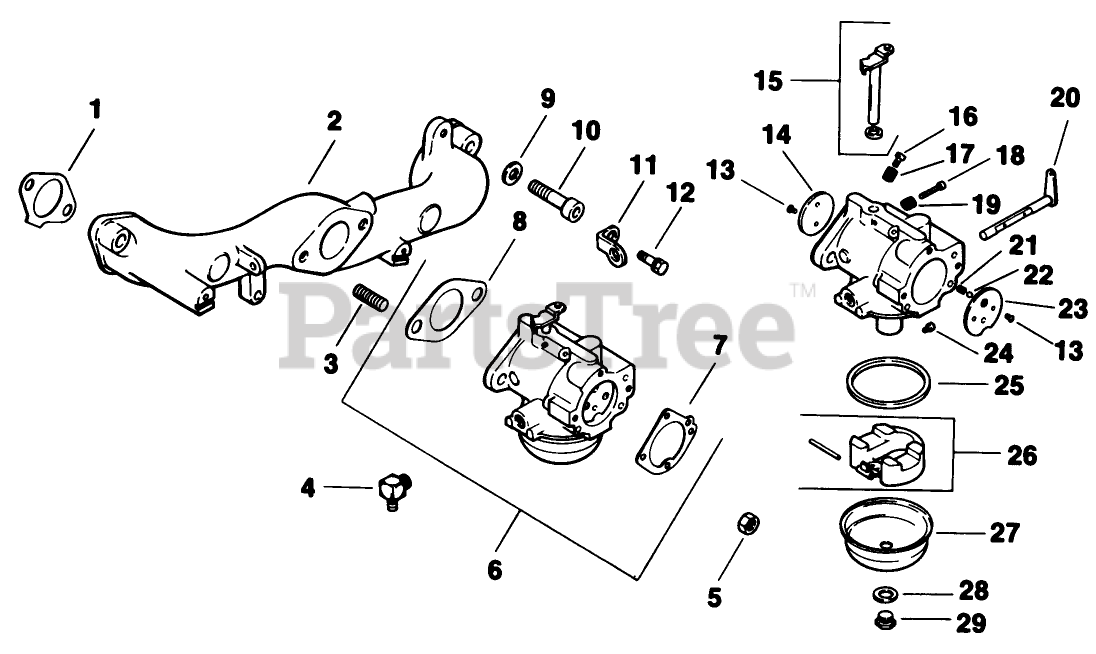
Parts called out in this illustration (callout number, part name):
1	Gasket-Intake
2	Manifold-Intake
4	Connector
6	Carburetor Kit w/Linkage (Incl. Ref. #7-9,14-30)
7	Gasket
8	Carburetor Assembly Ref.
9	Gasket
10	Screw
11	Screw
12	Strap Lifting
13	Screw
14	Screw-Throttle Plate (Only On: 72042,72043,72062,72063)
15	Plate-Throttle
16	Shaft Assembly
17	Needle-Idle Fuel Adj.
19	Screw-Idle Speed Adj.
20	Spring-Idle Speed
21	Lever-Choke
22	Spring-Choke Friction
23	Ball-Choke Friction
24	Plate-Choke
25	Jet-Main
26	Gasket
27	Kit-Float
28	Bowl-Fuel
29	Screw-Bowl Retainer
30	Gasket-Retainer Screw
